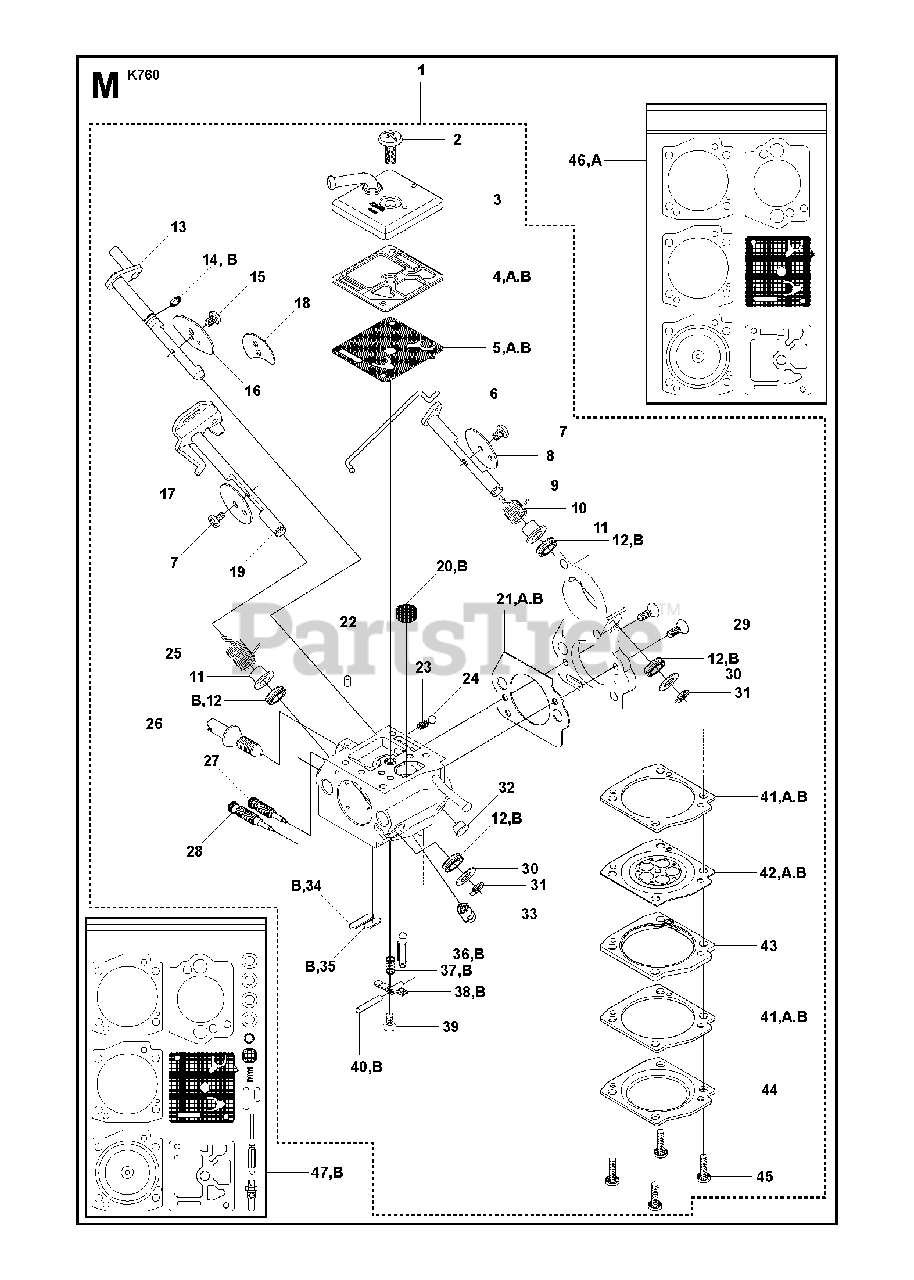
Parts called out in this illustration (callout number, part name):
1	CARBURETTORZama C3-EL43A, Incl. 2 - 43
5	DIAPHRAGM PUMP
18	CHOKE VALVEJapan only
40	PIN RETAINING SCREW
42	DIAPHRAGM ASSY
46	GASKET KITIncl. 4-5, 21, 41, 42
47	GASKET KITIncl. 4-5, 12, 14, 20, 21, 34-38, 40-42
